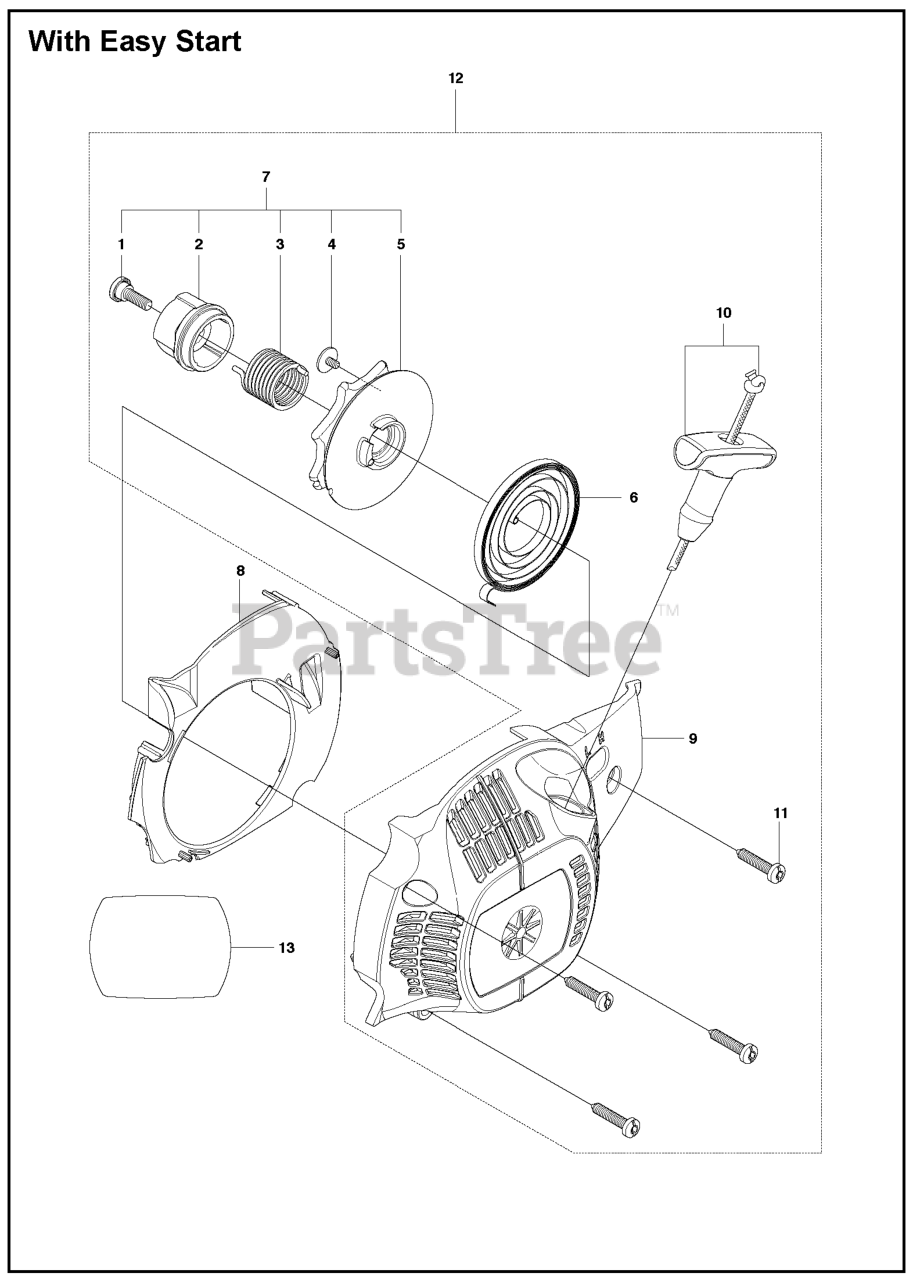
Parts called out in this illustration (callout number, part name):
1	SCREW SHOULDER
2	HUB STARTER EPS
3	SPRING EPS
4	SCREW
5	PULLEY STARTER EPS
6	SPRING STARTER
7	KIT EPS STARTER
8	BAFFLE
9	FAN HOUSING
10	STARTER ROPE W/HANDLE
11	SCREW M5.38-14X22.225MM
12	KIT COMPLETE EPS
13	Decals
